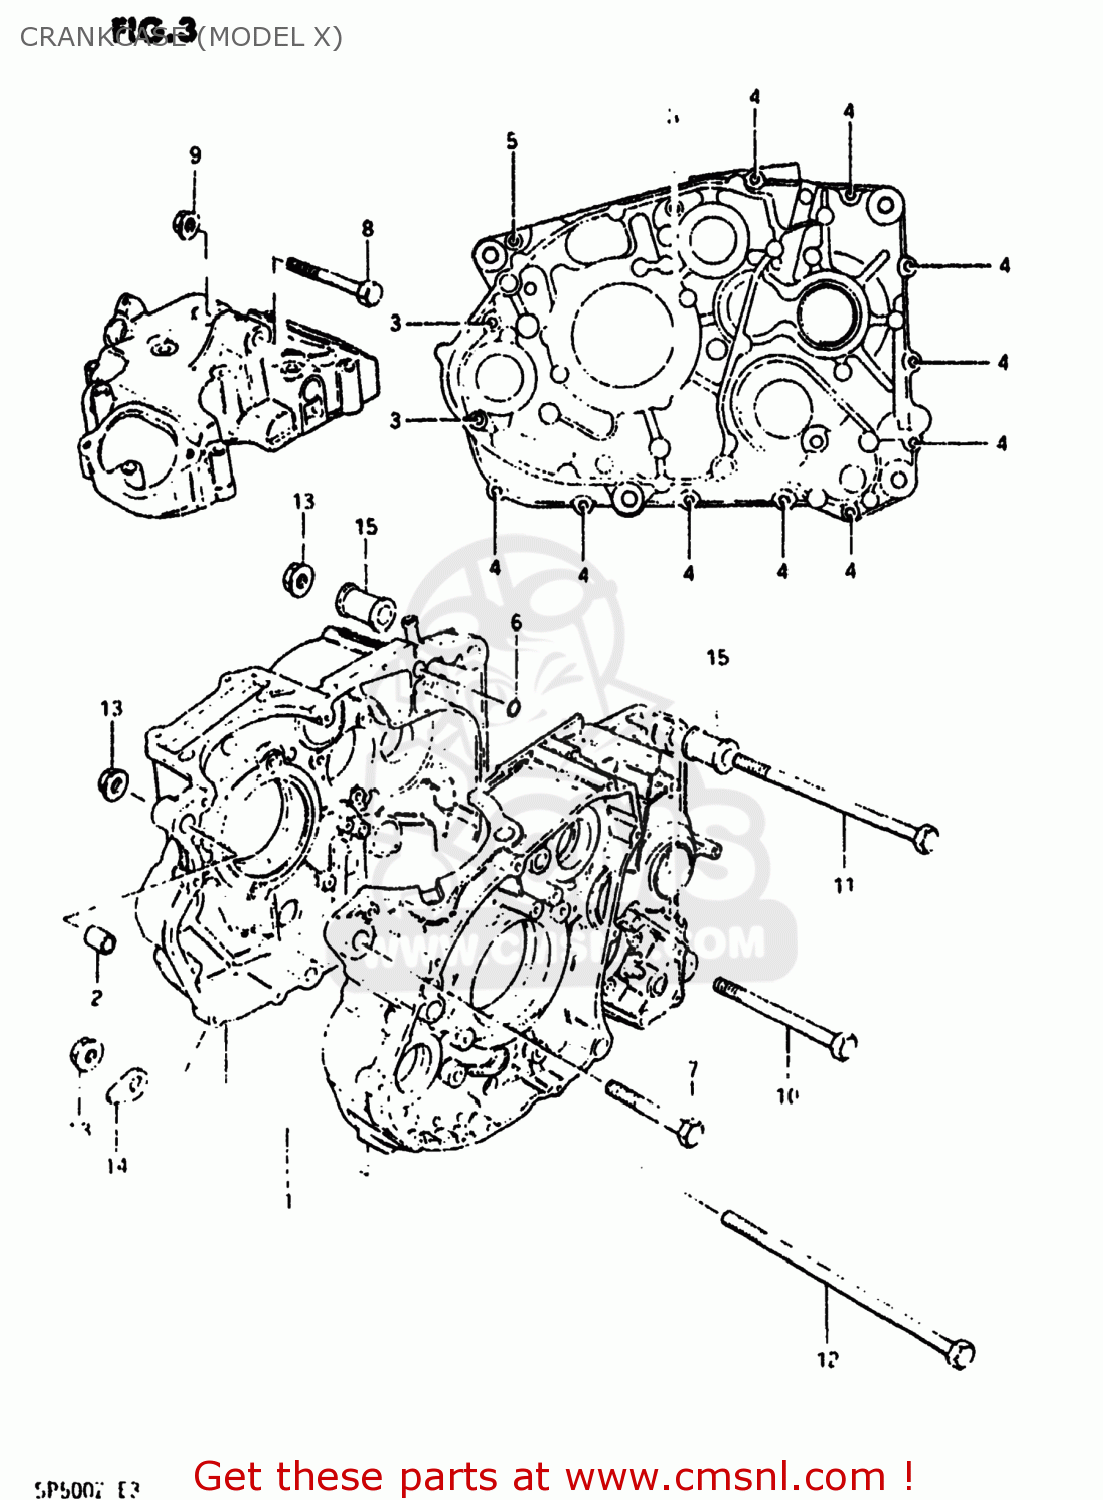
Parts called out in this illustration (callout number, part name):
1	CRANKCASE SET
2	PIN
3	SCREW 6X60
4	SCREW
5	SCREW 6X30
6	O-RING
7	BOLT(10X70)
8	BOLT
9	NUT
10	BOLT
11	BOLT
12	BOLT
13	NUT
14	WASHER
15	SPACER
